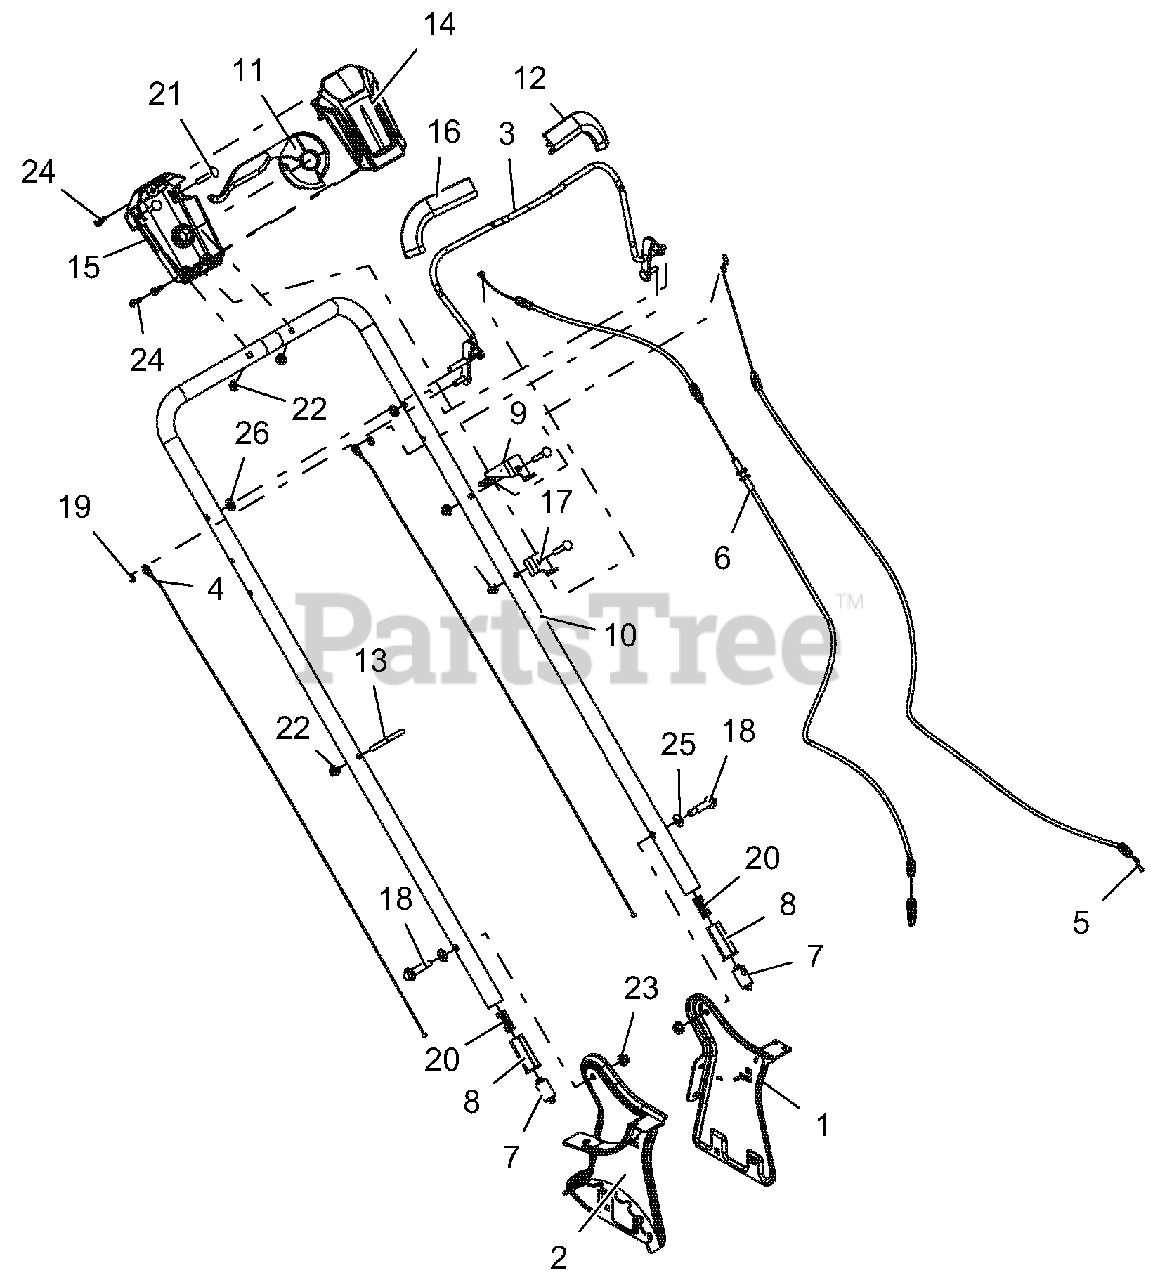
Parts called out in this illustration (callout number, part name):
1	SUPPORT, LH HANDLEBAR
2	SUPPORT, RH HANDLEBAR
3	WLDMT, OPC BAIL
4	CABLE, LM HANDLE ADJUST
5	CABLE, OPC
6	CABLE, DRIVE CONTROL
7	PLUNGER, HANDLEBAR LOCKING
8	INSERT, HANDLEBAR ADJUST
9	BRKT, CABLE ANCHOR
10	HANDLEBAR, LM
11	HANDLE, DRIVE CONTROL
12	GUARD, FINGER - LH
13	HOLDER, RECOIL CORD
14	HOUSING, UPPER DRIVE CONTROL
15	HOUSING, LOWER DRIVE CONTROL
16	HAND GRIP W/ DECAL
17	BRKT, CABLE - DRIVE
18	BLT-SHLDR, .50X1.15X.312-18GR5
19	RG-RTNG-EXT .250X.010
20	SPRING, COMPRESSION
21	@BLT-RDHDSQNK .25-20X1.50 G5YZ
22	@NUT-LK-TOP-FLG .25-20 YWZC
23	@NUT-LK-TOP-FLG .31-18 YWZC
24	SCR-TAP 12-14X.75PLSTITE @BLZC
25	WSHR,.385X.745X.030 STL YWZC
26	@WSHR-FL-STL.344X.688X.065YWZC
